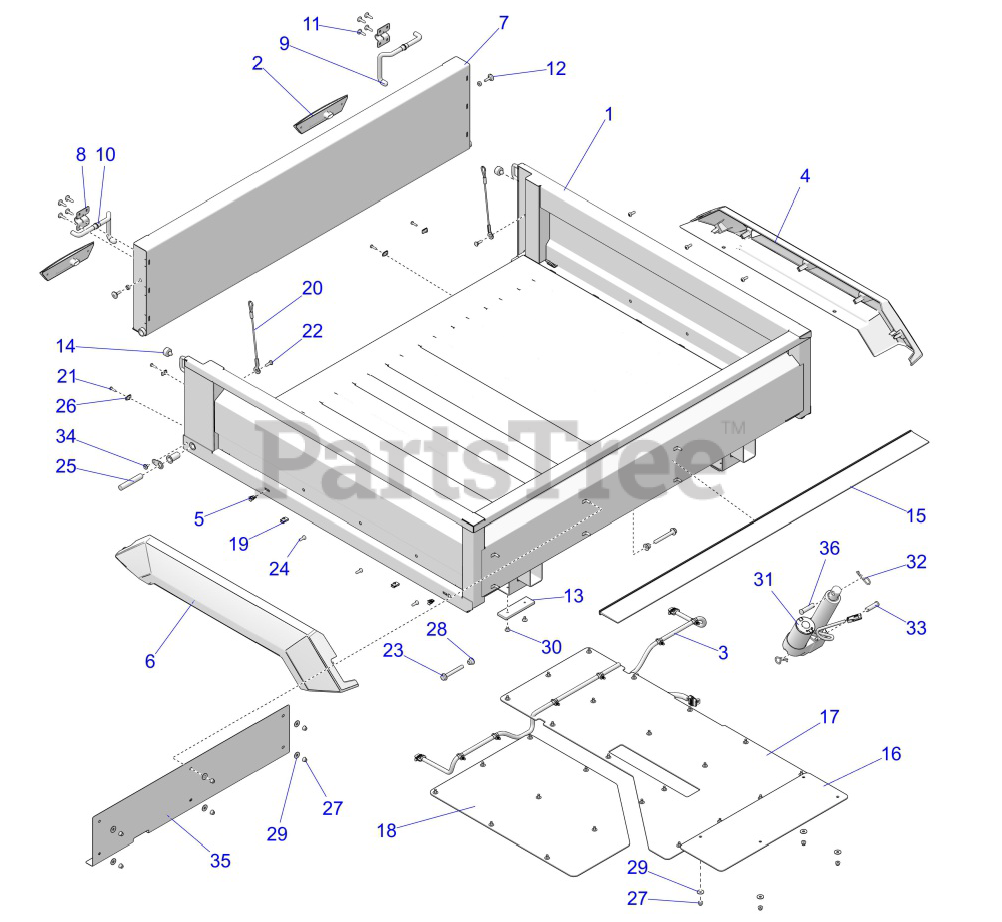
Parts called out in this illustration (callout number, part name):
1	WELD-BOX,ARNS,GRVLY RED
2	ASM-TAILLIGHT
3	HARNESS,BOX,ARNS
4	FLARE-BOX,LH,ARIENS
5	CLIP, DASH TRIM METAL
6	FLARE-BOX,RH,ARIENS
7	TAILGATE, RED
8	BRKT-TAILGATE LATCH
9	CAP, TAILGATE LATCH
10	BUSHING, TAILGATE LATCH
11	SCR-TXTH-M6X1.0X25 RIE
12	SCR-TXTH-M6X1.0X25 RIE,SHDR
13	BUMPER-BOX BASE
14	BUMPER, TAILGATE
15	TRIM-BOX
16	SHIELD-HEAT,EXHAUST,FRONT
17	SHIELD-HEAT,EXHAUST,REAR
18	SHIELD-HEAT,EXHAUST,SIDE
19	CLIP-U SPEED NUT
20	TAILGATE CABLE
22	BLT-SHLDR .188X.188X.25-20
23	SCR-HXFL-M10X1.25X80 8.8 ZOD
24	SCR-TXPH-#14 X .75 HI-LO RIE
25	PIN-TAILGATE MOUNT
26	NUT-U,CHIMNEY,10-24-B
27	NUT-M6 FLANGE,NYLOK
28	NUT-M10X1.25,FLG,NYLOC-OLIVE D
30	RIVET(50) *
31	ACTUATOR,BOX LIFT,CMPT,TTN
32	CLIP, HITCH PIN
33	PIN, CLEVIS
34	SCR-M6X1X16 TR/TX-M
35	SHIELD-HEAT,BOX,FRONT
36	PIN, CLEVIS BOX LIFT 2"
